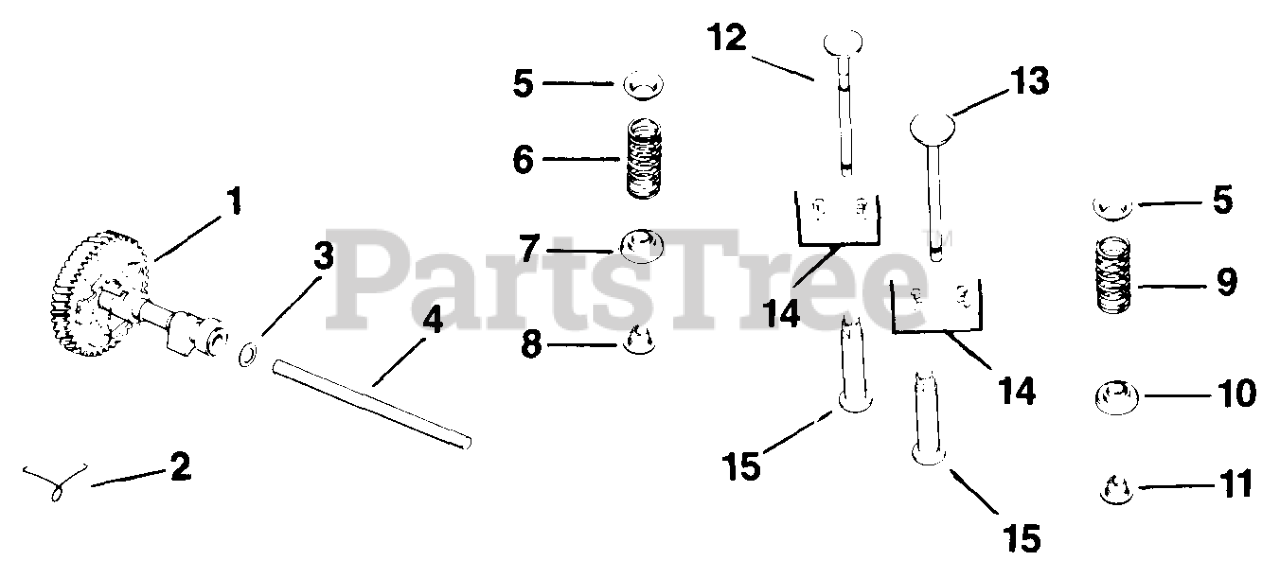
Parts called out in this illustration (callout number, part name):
1	CAMSHAFT - DISCONTINUED
2	SPRING, ACTUATING-DISCONTINUED
3	SPACER (.005")
3	SPACER (.010")
4	PIN, CAMSHAFT - DISCONTINUED
5	RETAINER, SPRING
6	SPRING, INTAKE VALVE - DISCONTINUED
9	SPRING, INTAKE VALVE - DISCONTINUED
14	KIT, RETAINER
